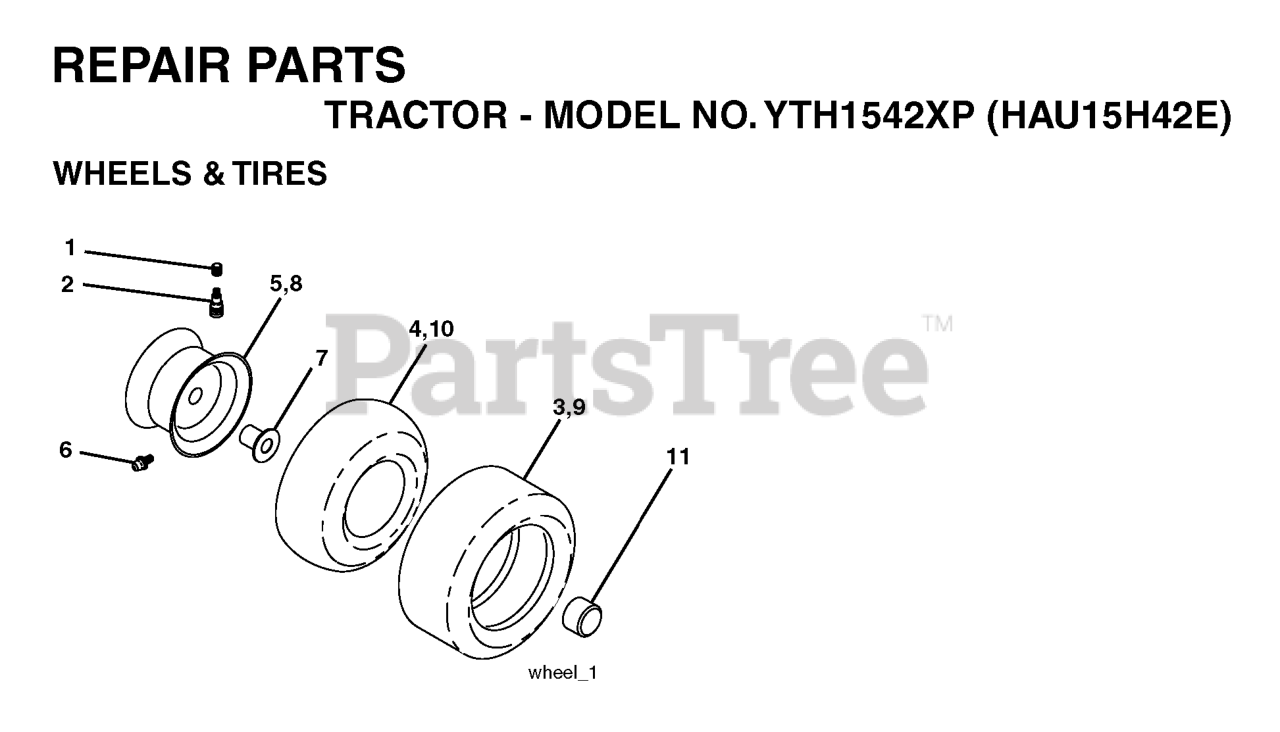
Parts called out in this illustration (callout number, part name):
2	VALVE STEM LT
3	TIRE HEAVY DUTY
4	TUBE.5.3/4.5/6
5	RIM ASM 6" FRONT SILVER
6	FITTING LT
7	BEARING T
8	RIM ASM 8" REAR SILVER
9	TIRE.TS.20X10-8
10	TUBE
11	CAP, AXLE BLK
